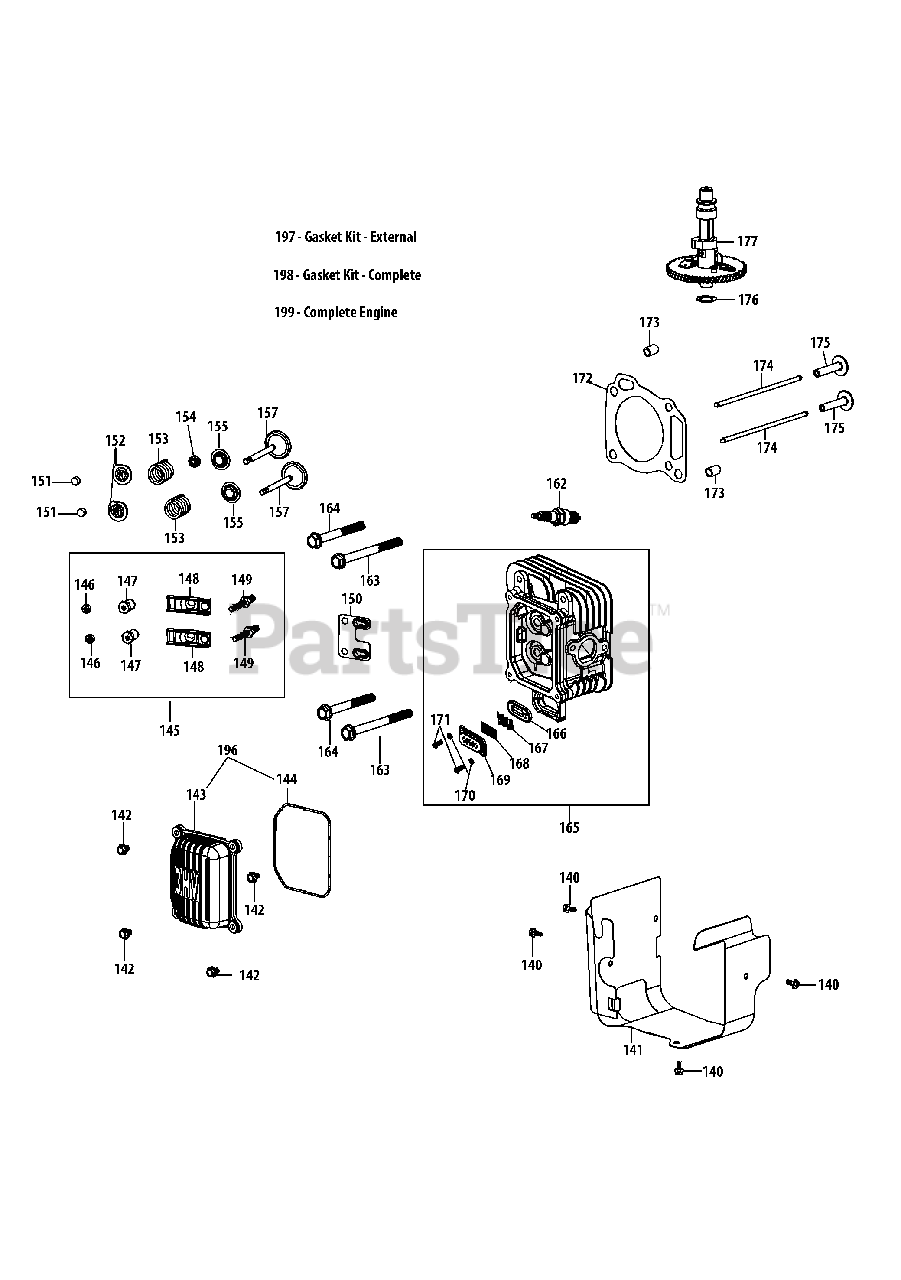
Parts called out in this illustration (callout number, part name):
140	Bolt M5×10
142	Valve Cover Bolt
143	Valve Cover
144	Valve Cover Ring
145	Rocker Arm Assembly
146	Jam Nut
147	Fulcrum Nut
148	Rocker Arm
149	Rocker Arm Stud
150	Push Rod Guide
151	Exhaust Valve Adjuster
152	Exhaust Valve Spring Retainer
153	Valve Spring
154	Intake Valve Seal
155	Valve Spring Retainer
157	Valve Kit
162	Spark Plug/F6Rtc
163	Bolt M10×1.25×85
164	Bolt /M10×1.25×65
165	Cylinder Head Kit
165	Cylinder Head Asm
166	Air Valve Core
167	Strainer Clip
168	Second Air Valve Filter Element
169	The Air Valve Bonnet
170	Washer
171	Screw M5×12
172	Cylinder Head Gasket
173	Cylinder Head Dowel 12×16
174	Push Rod Kit
175	Tappet
176	Camshaft Thrust Washer
177	Camshaft Assembly
196	Valve Cover Kit
197	Gasket Kit - External
198	Gasket Kit - Complete
199	Complete Engine
